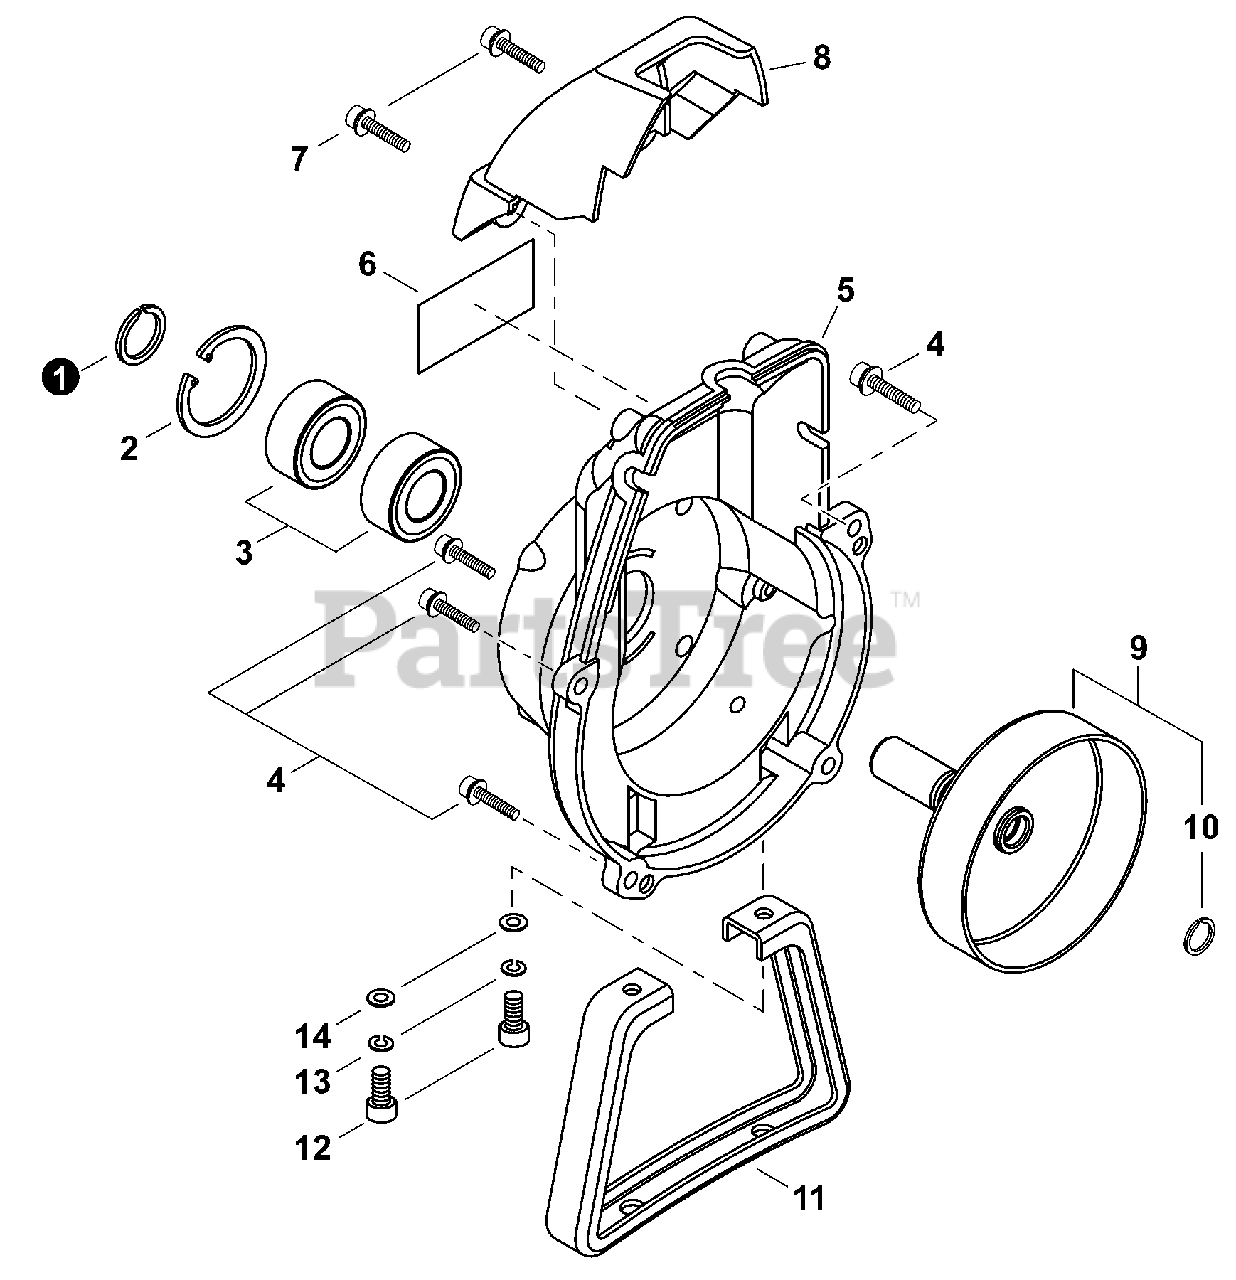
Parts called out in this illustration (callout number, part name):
1	RING, SNAP
2	RING, SNAP ?32
3	BEARING, BALL 6002 DDU
4	BOLT M5x20
5	COVER, FAN
6	LABEL - TRADE
7	BOLT M4x16
8	GUARD, TOP
9	DRUM, CLUTCH
10	RING, SNAP ?11.4
11	STAND
12	BOLT 5
13	WASHER, SPRING 5
14	WASHER 5.5x12x0.8
